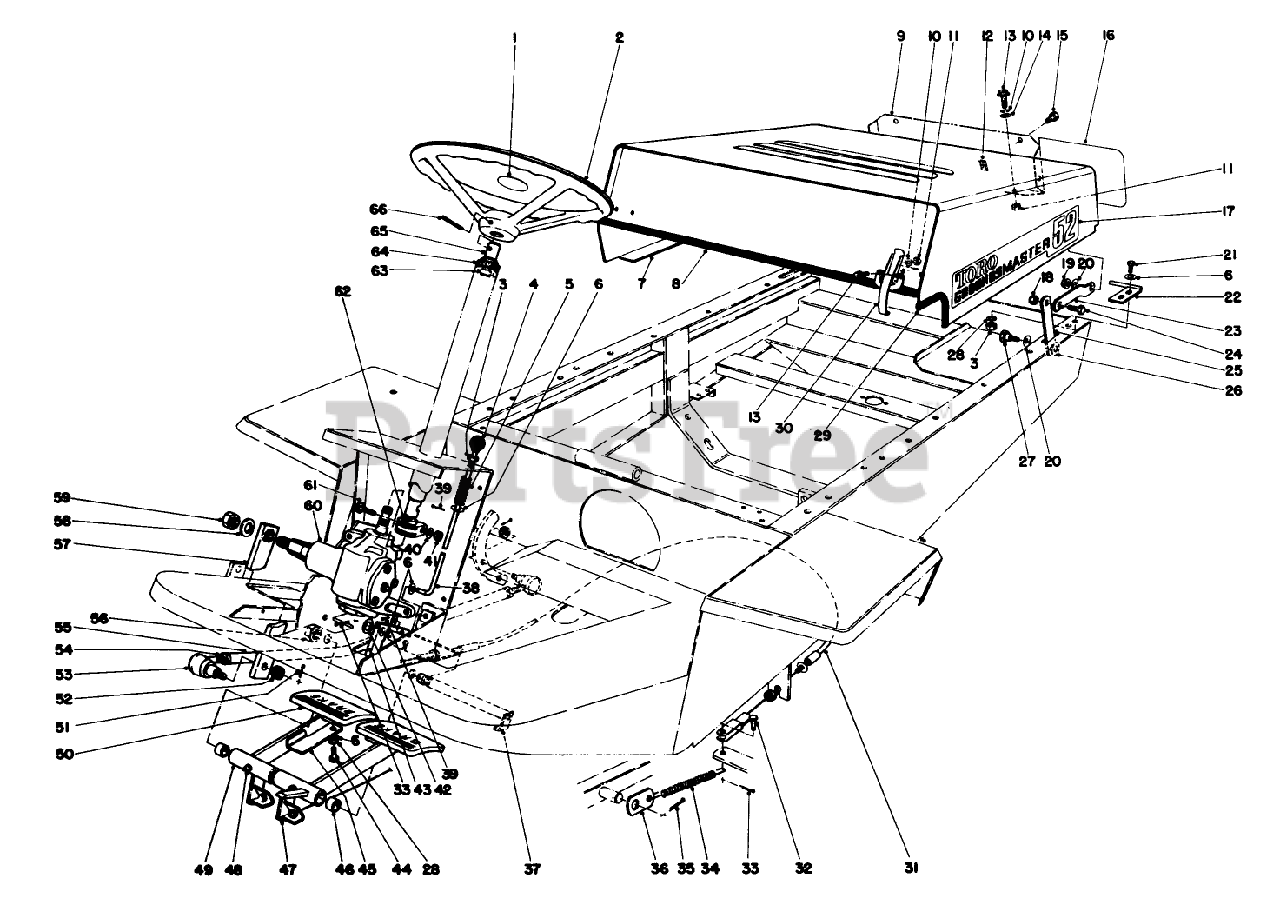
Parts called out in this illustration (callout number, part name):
1	STEERING WHEEL CAP
2	STEERING WHEEL
3	NUT-HEX
5	Spring
6	WASHER-FLAT
7	Hood
8	Trim
9	HOOD SCREEN B
10	WASHER-LOCK
11	NUT-HEX
12	NUT-CLIP,U
13	SCREW-SHWH
14	WASHER-FLAT
15	SCREW-PPHTF
16	HOOD DECAL
17	Decal-Groundsmaster
18	NUT-HEX
19	NUT-HF
20	WASHER-SPRING
21	SCREW-HH
22	PivotPin L.H.
23	Link Hood
24	SCREW-HH
25	Tie Hood
26	WASHER-FLAT
27	SCREW-SHOULDER
28	WASHER-LOCK
29	HOOD TRIM
30	HOOK TYPE CLAMP
31	RH BRAKE CABLE ASM
32	PIN-CLEVIS
33	PIN-COTTER
34	SPRING-EXTENSION
35	PIN-COTTER
36	BRAKE SPRNG STRAP R
38	Rod Brake Latch
39	PIN-COTTER
40	WASHER-LOCK
41	NUT-HEX
42	WASHER-FLAT
43	RACK WA
44	SCREW-HH
45	Latch Parking Brake
46	BUSHING
47	Brake Pedal L.H. (Incl. Ref. #46 & 48)
48	FITTING-GREASE
49	Brake Pedal R.H. (Incl. Ref. # 46 & 48)
50	PAD-BRAKE
51	PIN-COTTER
52	NUT-SLOTTED
53	Socket Assembly R.H. (Incl. Ref. #52)
54	NUT-JAM
55	FRONT STEERING TUBE B
56	NUT-LOCK, NI
57	Pitman Arm
58	WASHER-LOCK
59	NUT-JAM
60	Steering Gear
61	7/16-14 X 1-3/4 BOLT
62	CLAMP STRG COUPLING
63	BALL BRG
64	COVER-DUST
65	STRG SHAFT WA
66	PIN-ROLL
